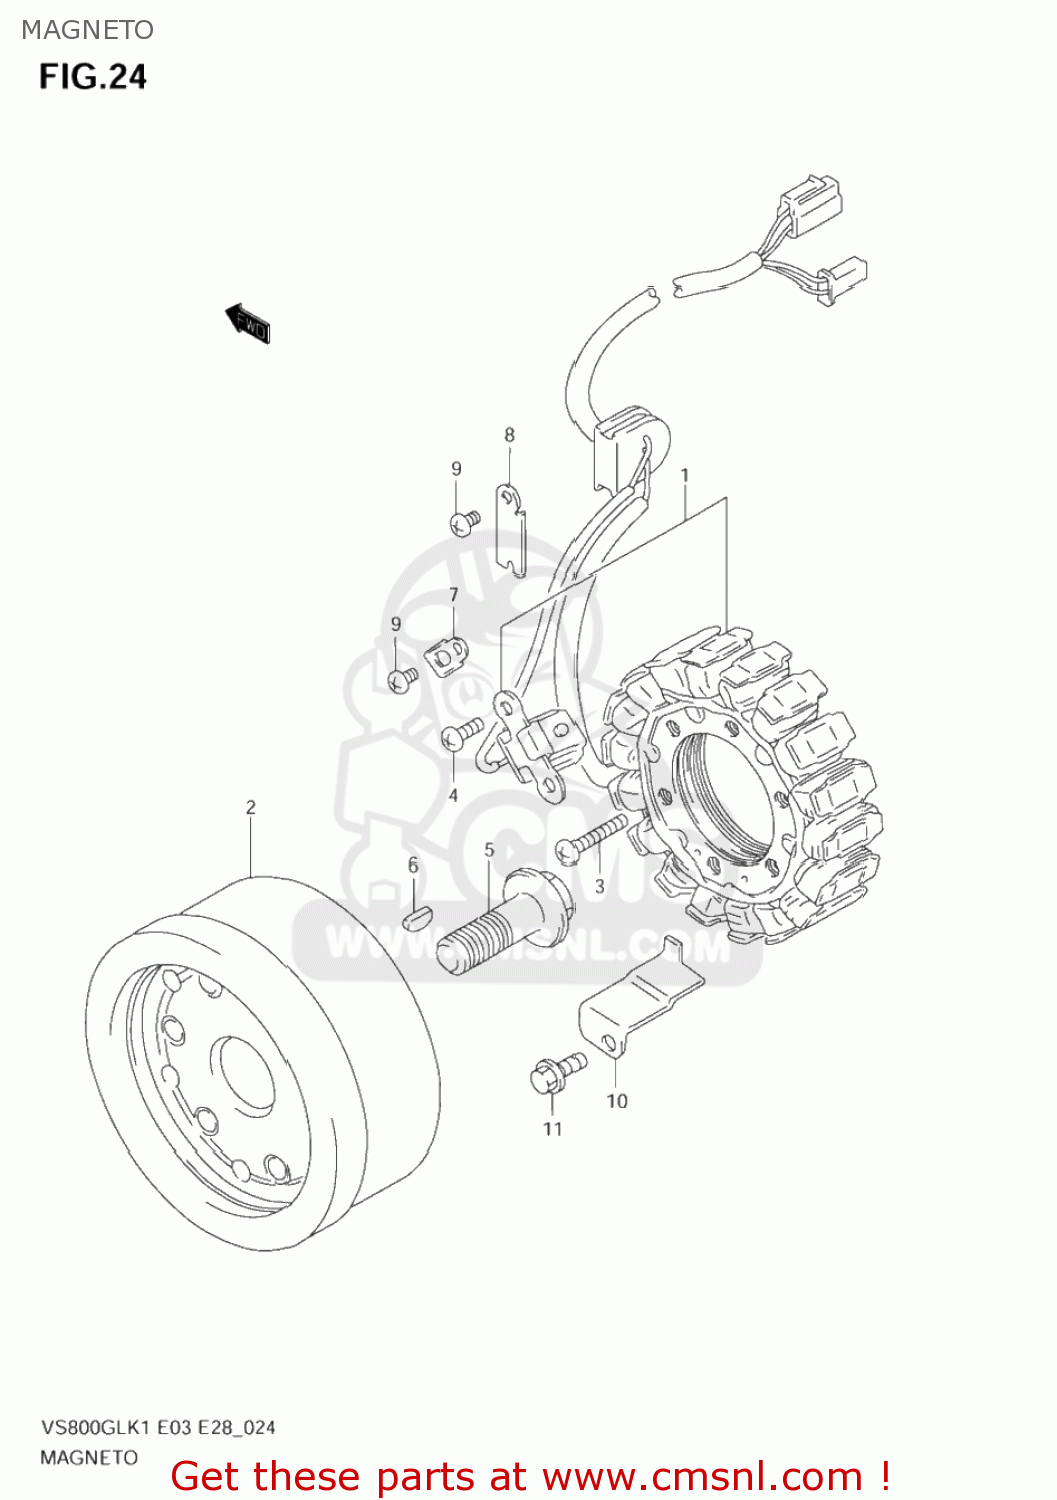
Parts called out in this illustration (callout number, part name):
1	STARTER ASSY
2	ROTOR ASSY
3	BOLT,G/S SWITC
4	SCREW
5	BOLT(14X43)
6	KEY
7	CLAMP,GENERATOR LEAD WIRE
8	CLAMP NO.1,MAGNETO READ WIRE
9	SCREW
10	CLAMP,MAGNETO LEAD WIRE
11	BOLT
